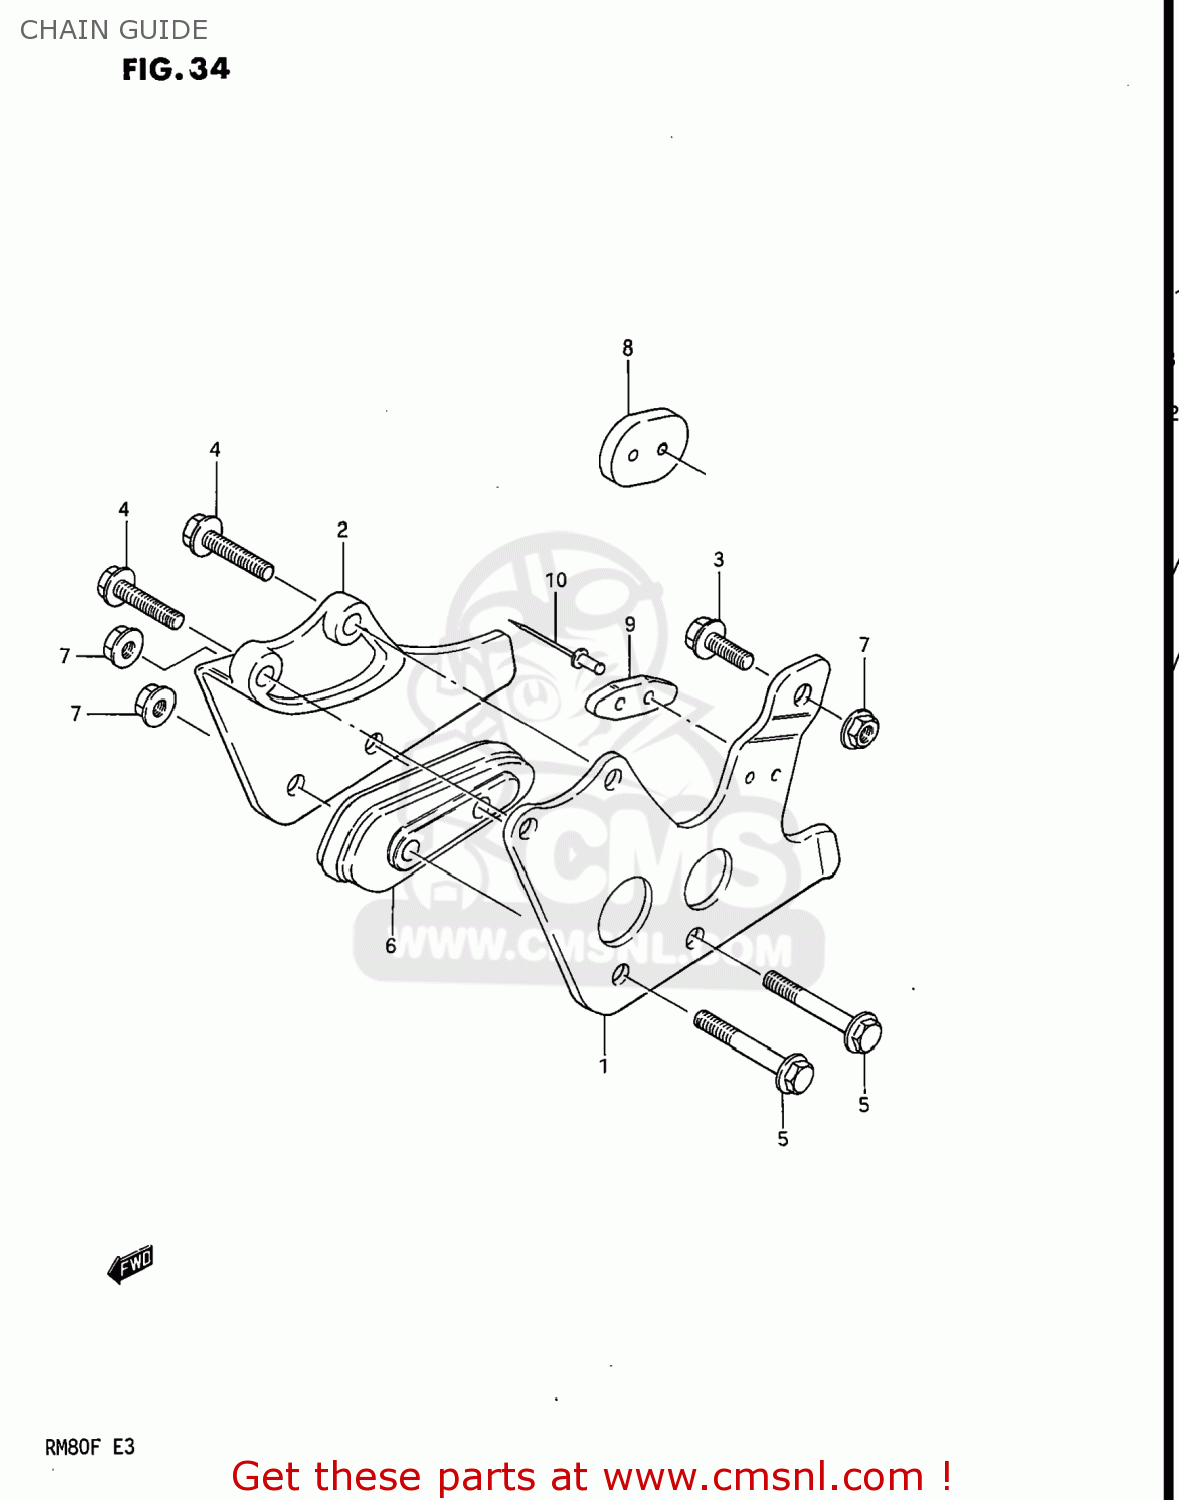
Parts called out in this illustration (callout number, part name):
1	GUIDE,CHAIN
2	PLATE,CHAIN GUIDE INNER
3	BOLT
4	BOLT
5	BOLT
6	DEFENSE,CHAIN GUIDE
7	NUT
8	PAD,DRIVE CHAIN GUIDE
9	PAD
10	RIVET
